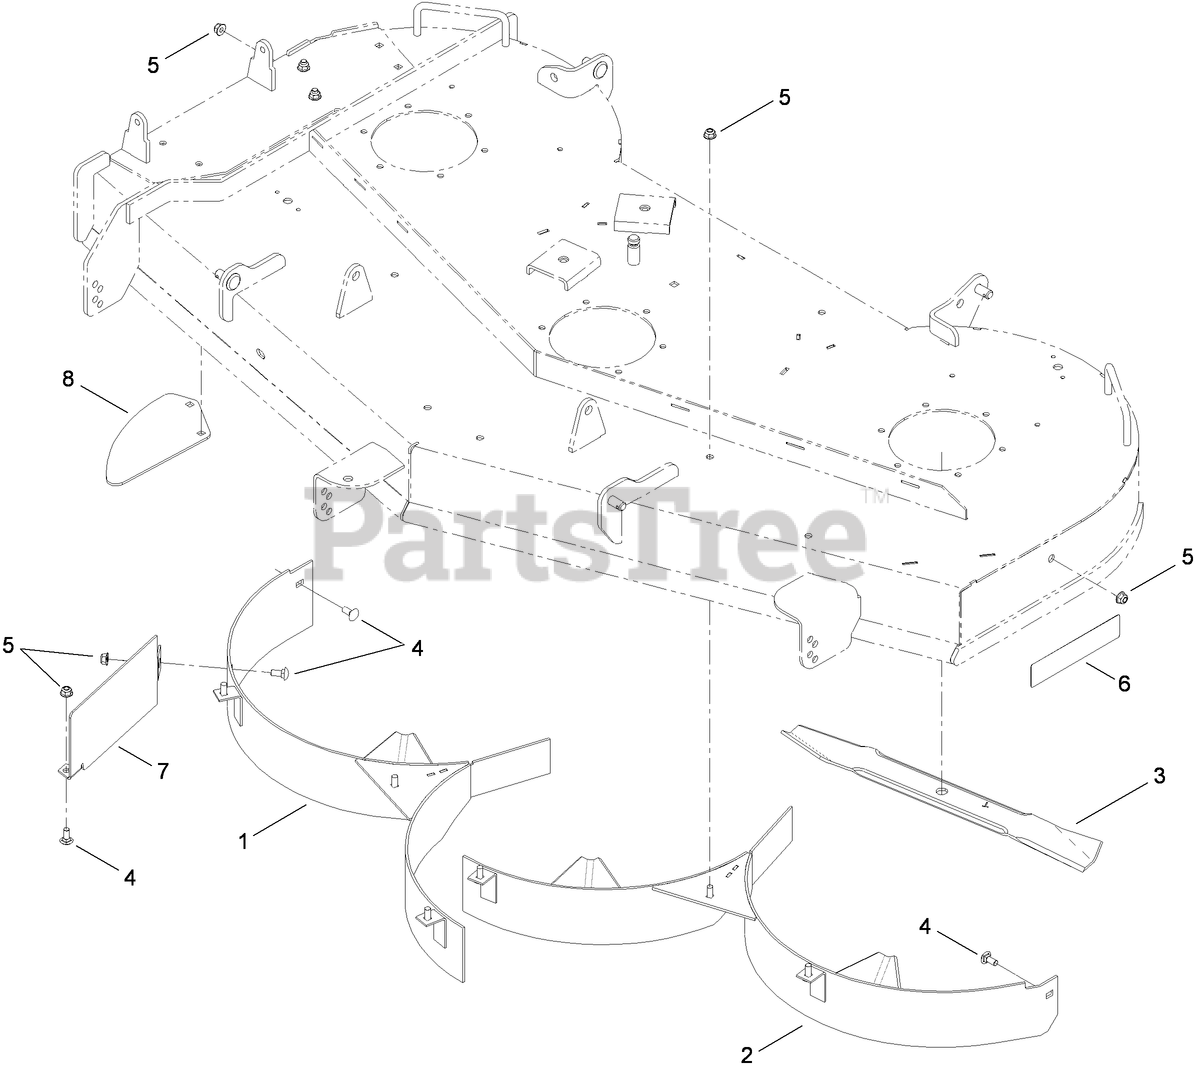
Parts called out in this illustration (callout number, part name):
1	BAFFLE-RECYCLER, RH
2	BAFFLE-RECYCLER, LH
3	BLADE-MULCH, 20.50 INCH
4	BOLT-CARR
5	NUT-HF, NI
6	DECAL-RECYCLER, 60 INCH
7	GUARD-BAFFLE
8	PLATE-FILLER
